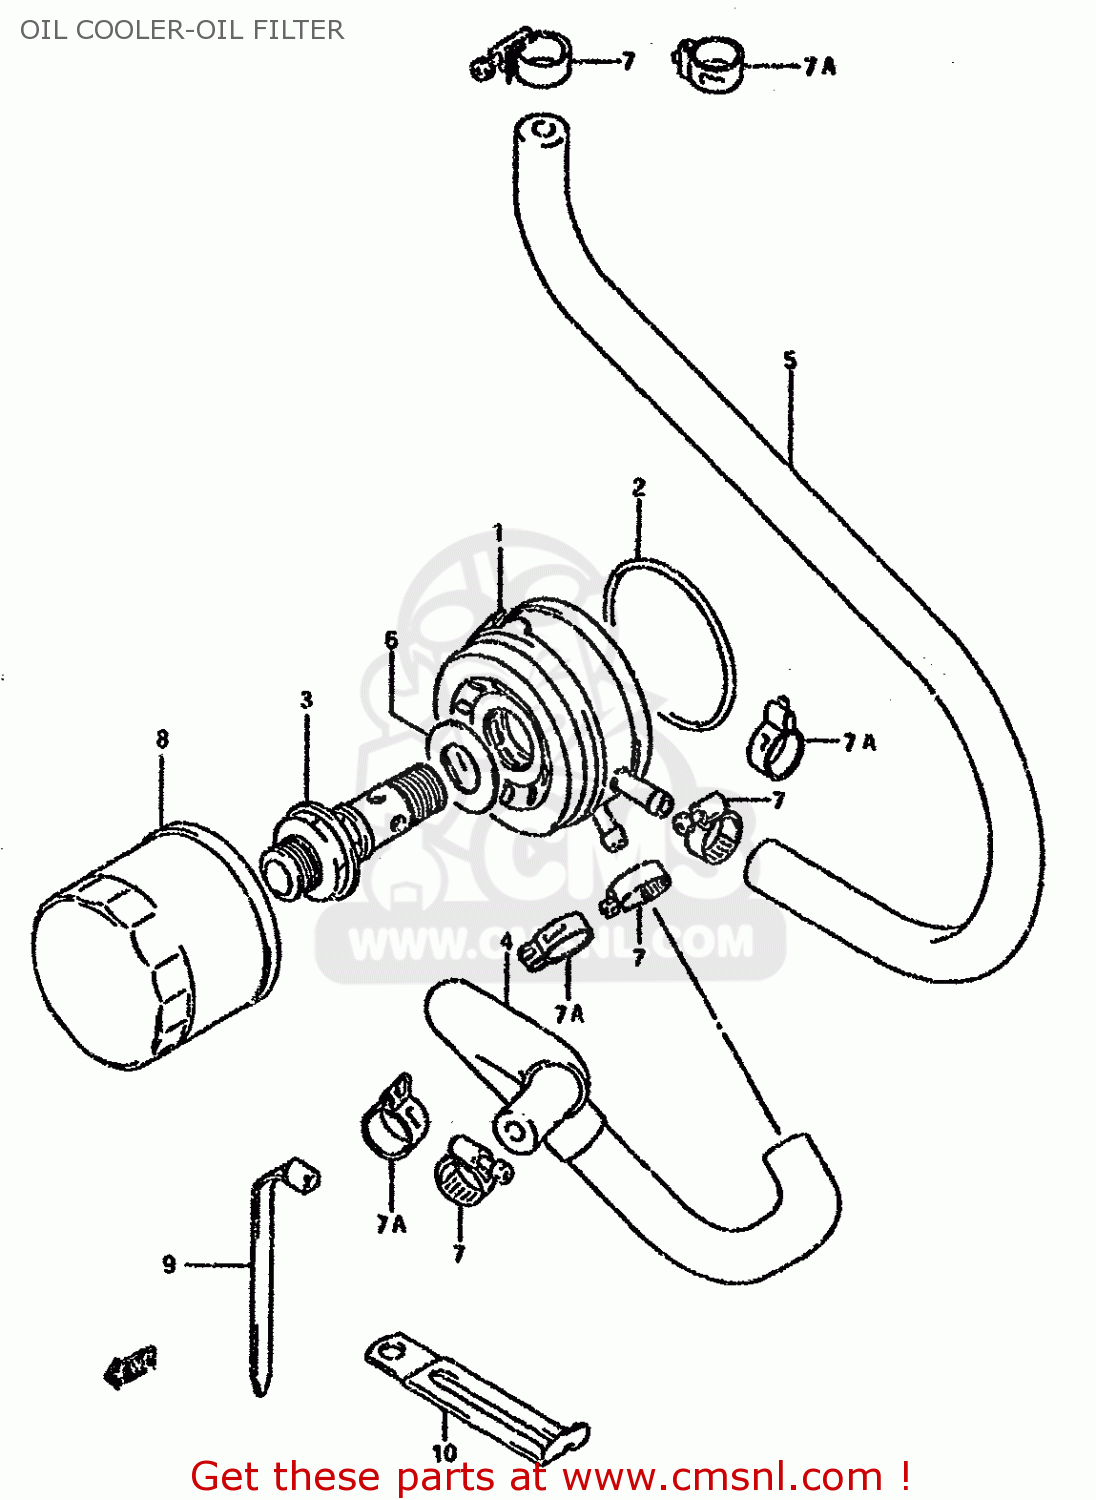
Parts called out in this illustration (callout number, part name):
1	COOLER ASSY,OIL
2	O RING(D:3.1,ID:63.9)
3	BOLT,OIL COOLER UNION
4	HOSE,OIL COOLER WATER IN
5	HOSE,OIL
6	SHIM
7	CLAMP
7A	CLIP
8	FILTER ASSY,ENGINE OIL
9	CLAMP(L:165)
10	CLAMP
